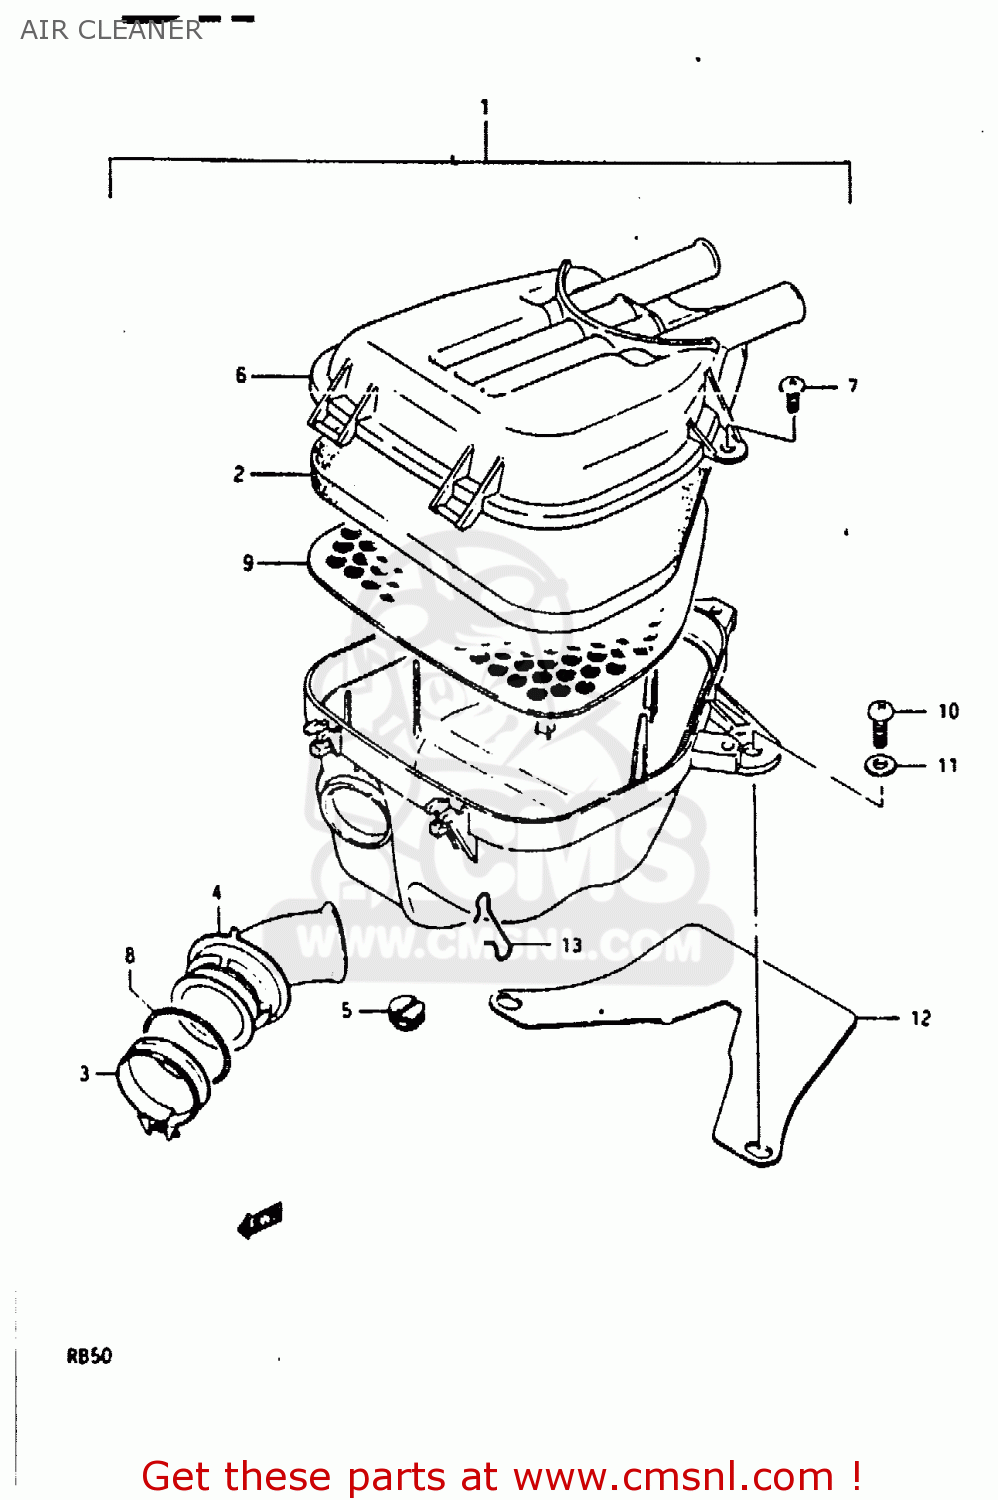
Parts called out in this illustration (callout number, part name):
1	CLEANER ASSEMBLY,AIR
2	FILTER
3	CLAMP
4	TUBE,AIR CLEANER OUTLET
5	CAP,DRAIN
6	CAP
7	SCREW 5X10
8	SPRING,GARTER
9	TRAP
10	SCREW
11	WASHER
12	GUARD,WATER
13	CLIP
